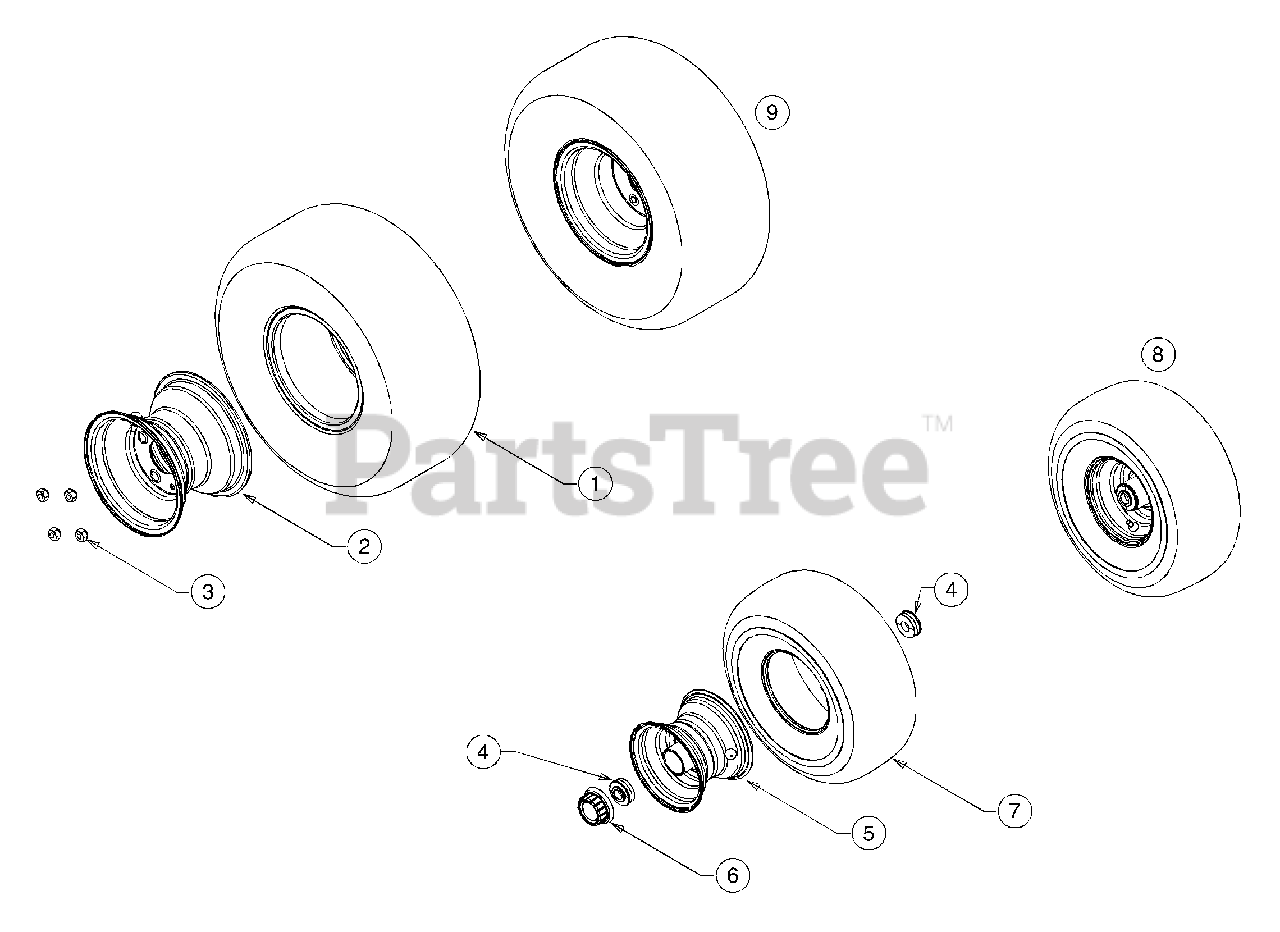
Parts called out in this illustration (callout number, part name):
1	Tire, Turf Saver Tread, Cub Cadet 20 x 9 x 8
3	Lug Nut, 7/16-14
4	Bearing, Ball, .75 ID x 1.75 OD
5	Rim Assembly, 6 x 4.5 (Included, Bearings, Spacer and Valve)
6	Hub Cap
7	Tire, Turf Saver Tread, Cub Cadet 15 x 6 x 6
8	Wheel Assembly,Cub Cadet 15 x 6 x 6 (assembly not available)
9	Wheel Assembly,Cub Cadet 20 x 9 x 8 (assembly not available)
